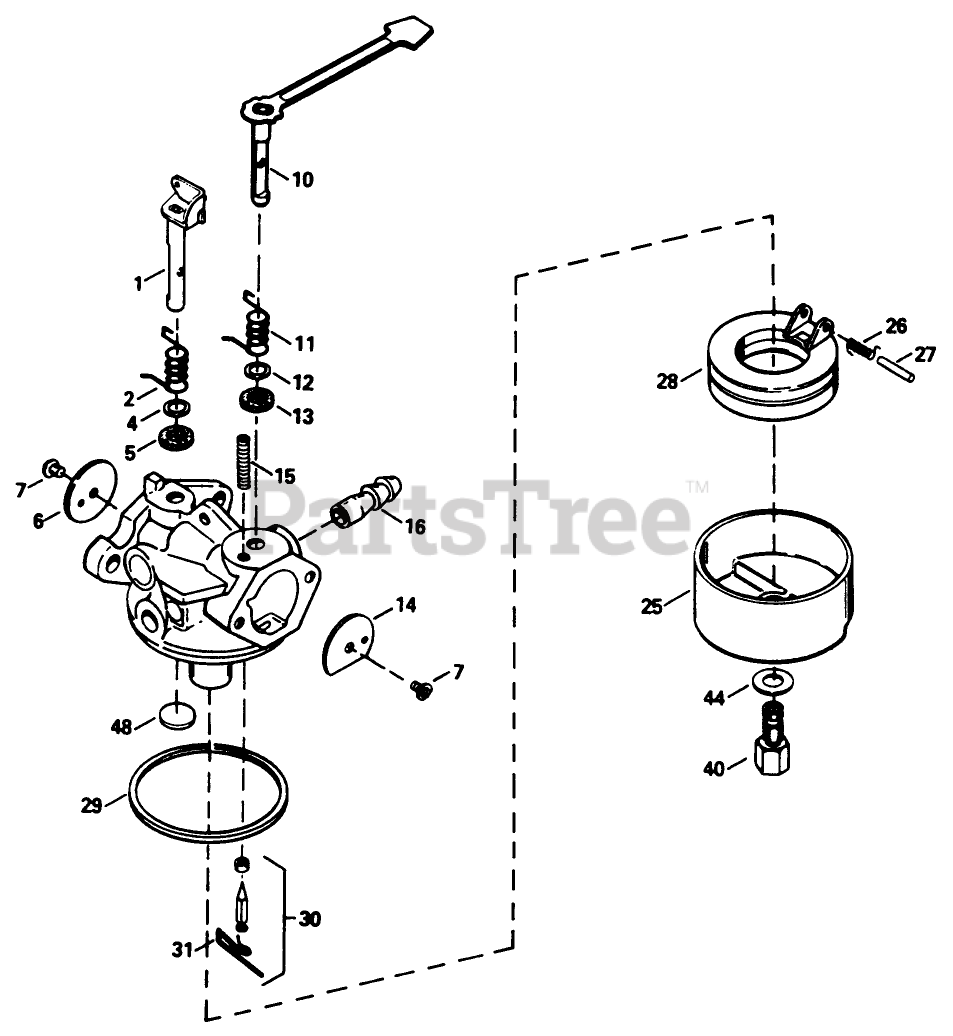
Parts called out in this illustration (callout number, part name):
1	Throttle Shaft Lever Asm.
2	Spring-Trottle, Return
4	Washer-Seal, Dust
5	Seal-Dust
6	Shutter-Throttle
7	Screw-Shutter
10	Choke Shaft and Lever ASM
14	Shutter-choke
15	Spring-Positioning, Choke
16	Fitting-Fuel
25	Bowl Float
26	Spring-Float, Dampening
27	Shaft-Float
28	Float
29	O Ring-Bowl, Float
30	Inlet Needle, Seat Clip Assy. (Incl. No. 13)
31	Clip-Spring
40	Nut-Float Bowl
44	Gasket-Bowl
48	Plug-Welch, Atmospheric Vent
